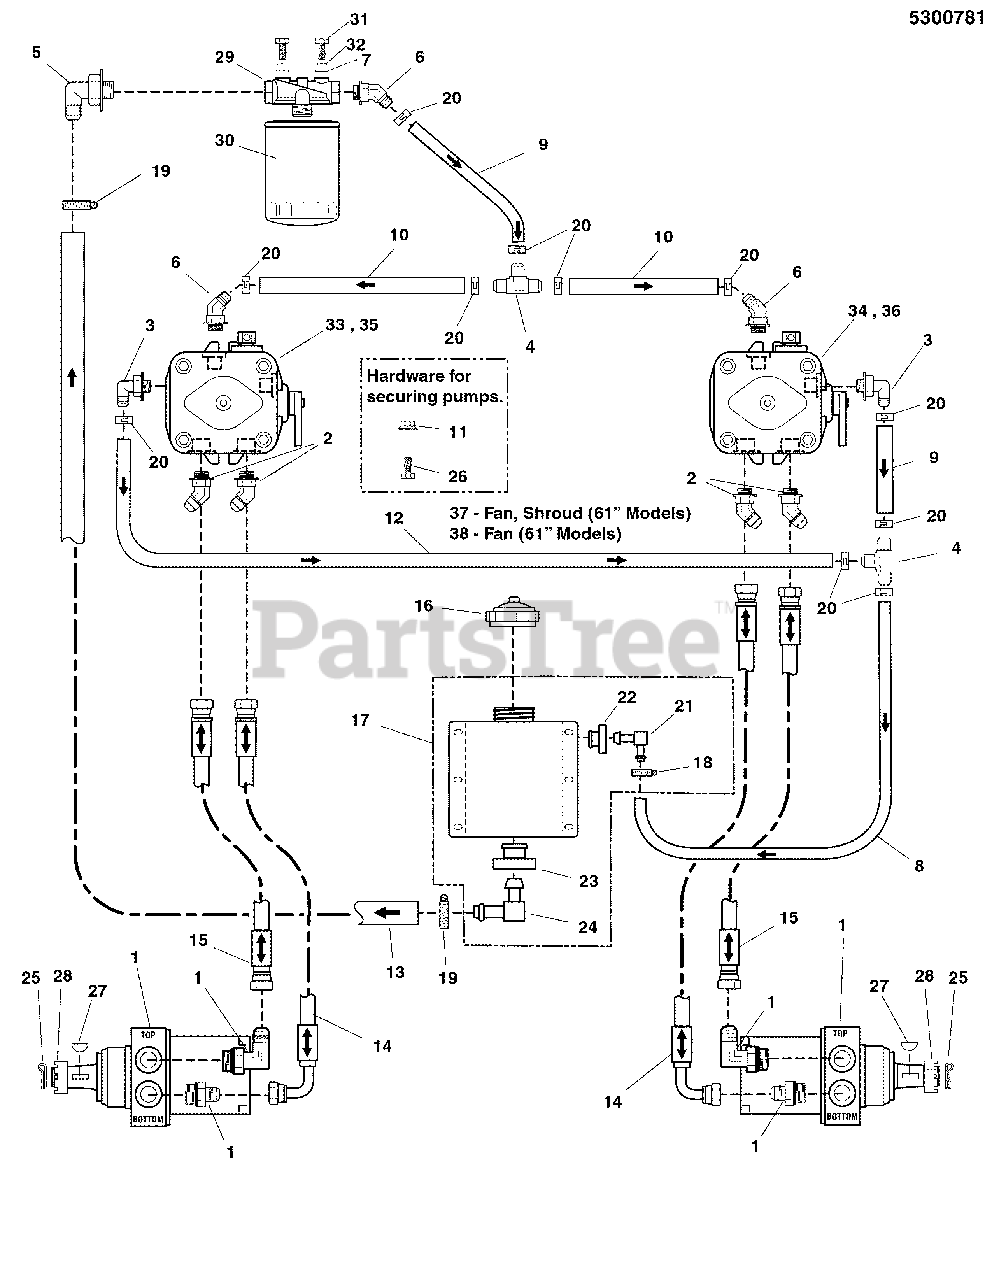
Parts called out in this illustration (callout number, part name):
2	FITTING, #8 JIC - #8 O-RING, 45 DEG.
3	ADAPTER, 90 DEG, 9/16-3/8 BARB
4	FITTING, TEE, 1/2" HOSE
5	ADAPTER, 90 DEG, 9/16-5/8 BARB
6	ADAPTER, 45 DEG, 9/16-3/8 BARB
7	WASHER, 1/4" LOCK
8	HOSE, 3/8" PUSH-LOCK, 18.50"
9	HOSE, 3/8" PUSH-LOCK, 6.50"
10	HOSE, 3/8" PUSH-LOCK, 6.00"
11	NUT, 3/8-16 HEX SERRATED FLANGE
12	HOSE, 3/8" PUSH-LOCK, 19.00"
13	HOSE, 5/8 PUSH-LOCK, 24.50"
14	HOSE ASSEMBLY (25")
15	HOSE ASSEMBLY (21")
16	CAP, HYDRAULIC
17	TANK, HYDRAULIC, ASSEMBLY
18	CLAMP, #4 HOSE, STAINLESS
19	CLAMP, #10 HOSE, STAINLESS
20	CLAMP, HOSE
21	FITTING, ELBOW, 3/8"
22	GROMMET
23	GROMMET
24	FITTING, ELBOW, 5/8"
25	PIN, COTTER, 1/8" X 2"
26	BOLT, 3/8-16 X 1-1/4" GD5
27	KEY
28	NUT, CASTLE, 1-20
29	FILTER HEAD, HYDRAULIC
30	FILTER, OIL
31	BOLT, 1/4-20 X 3/4" GD5 YZ
32	WASHER, 1/4 SAE
33	PE, 10CC HYDRAULIC PUMP - LH
34	PE, 10CC HYDRAULIC PUMP - RH
35	PUMP, HYDRAULIC - LH
36	PUMP, HYDRAULIC - RH
37	SHROUD, FAN
38	FAN, #51348,HYDRO-GEAR
